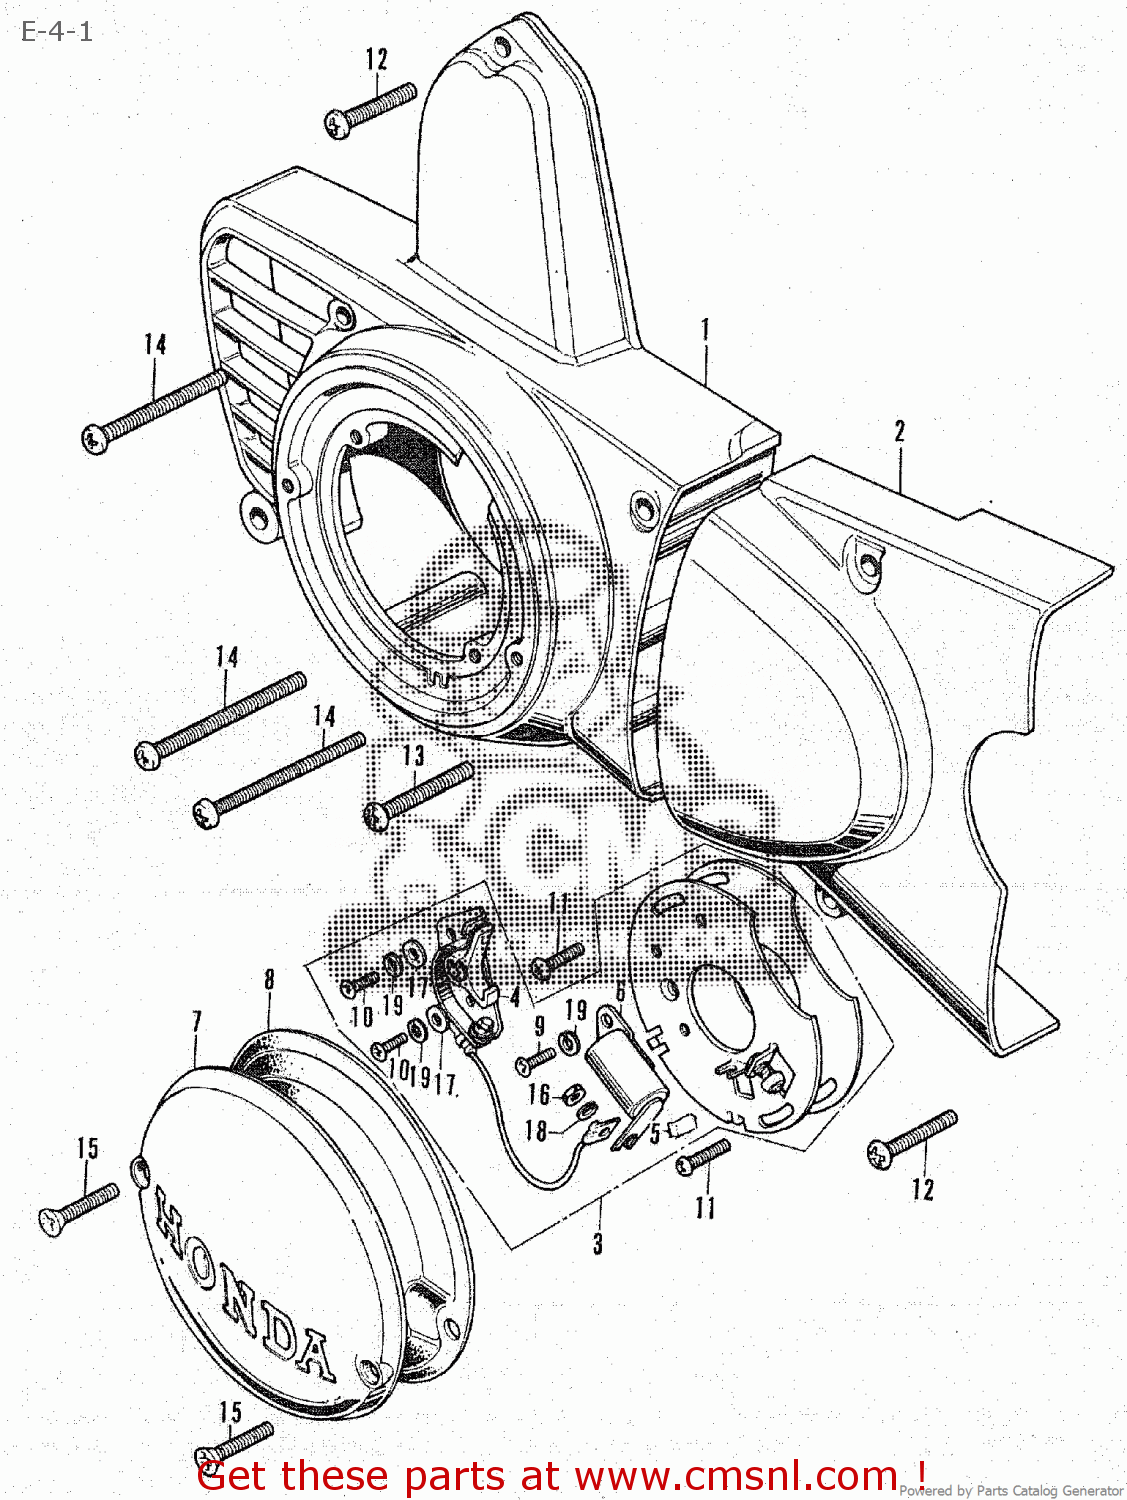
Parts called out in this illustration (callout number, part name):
1	COVER, L. CRANKCASE
2	COVER, L. RR.
3	BREAKER ASSY.
4	BREAKER CONTACT
5	FELT, OIL
6	CONDENSER
7	COVER BREAKER
8	PACKING COVER (NAS)
9	SCREW,PAN,4X5
10	SCREW,CROSS,4X6
11	SCREW,CROSS,5X12
12	SCREW,CROSS 6X20
13	BOLT,HEX 6X25
14	SCREW,PAN,6X50
15	SCREW,FLAT,5X20
16	NUT HEX 3MM
17	WASHER,4MM
18	SPG,WASHER3MM
19	WASHER,SPG.,4MM
